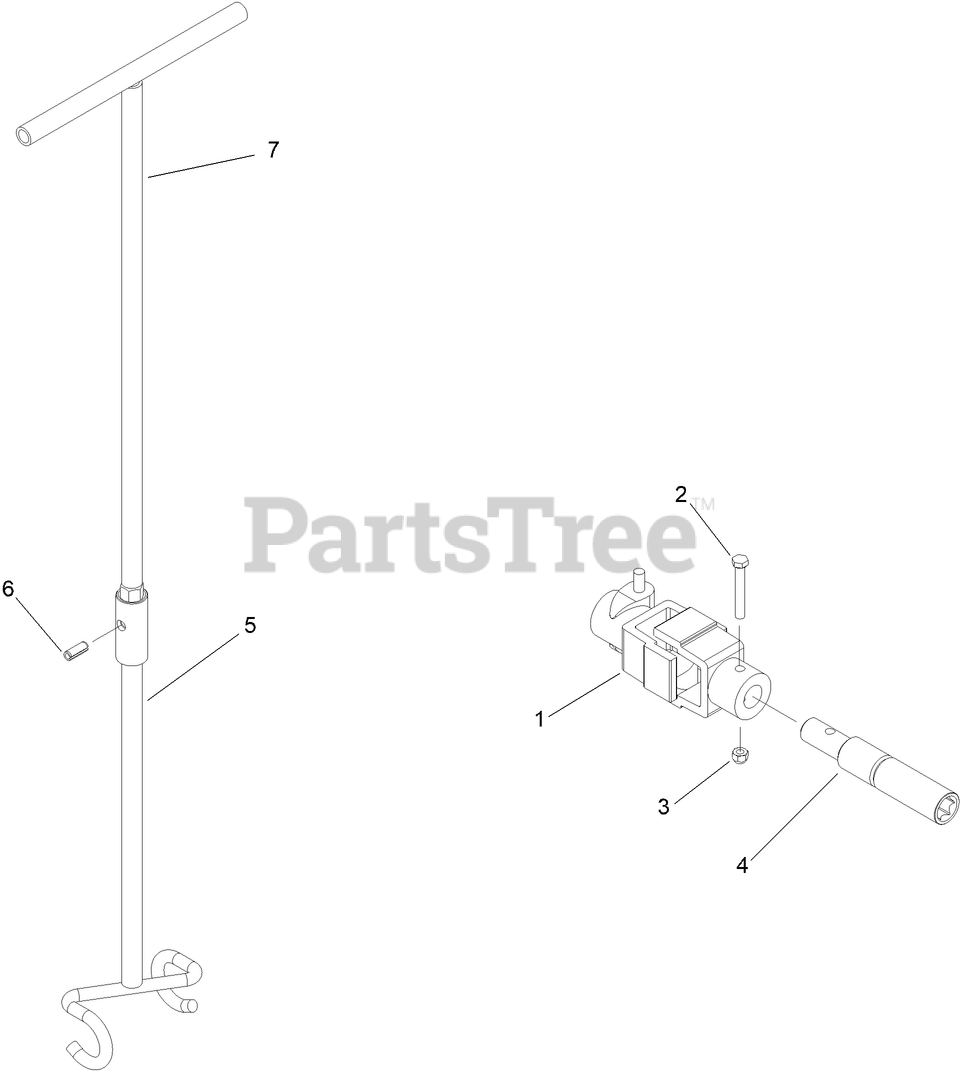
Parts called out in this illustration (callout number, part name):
2	SCREW-HH
3	NUT-HEX
4	ADAPTER
5	TOOL-GUIDE, ROD
6	PIN-ROLL
7	HANDLE-TOOL, GUIDE
